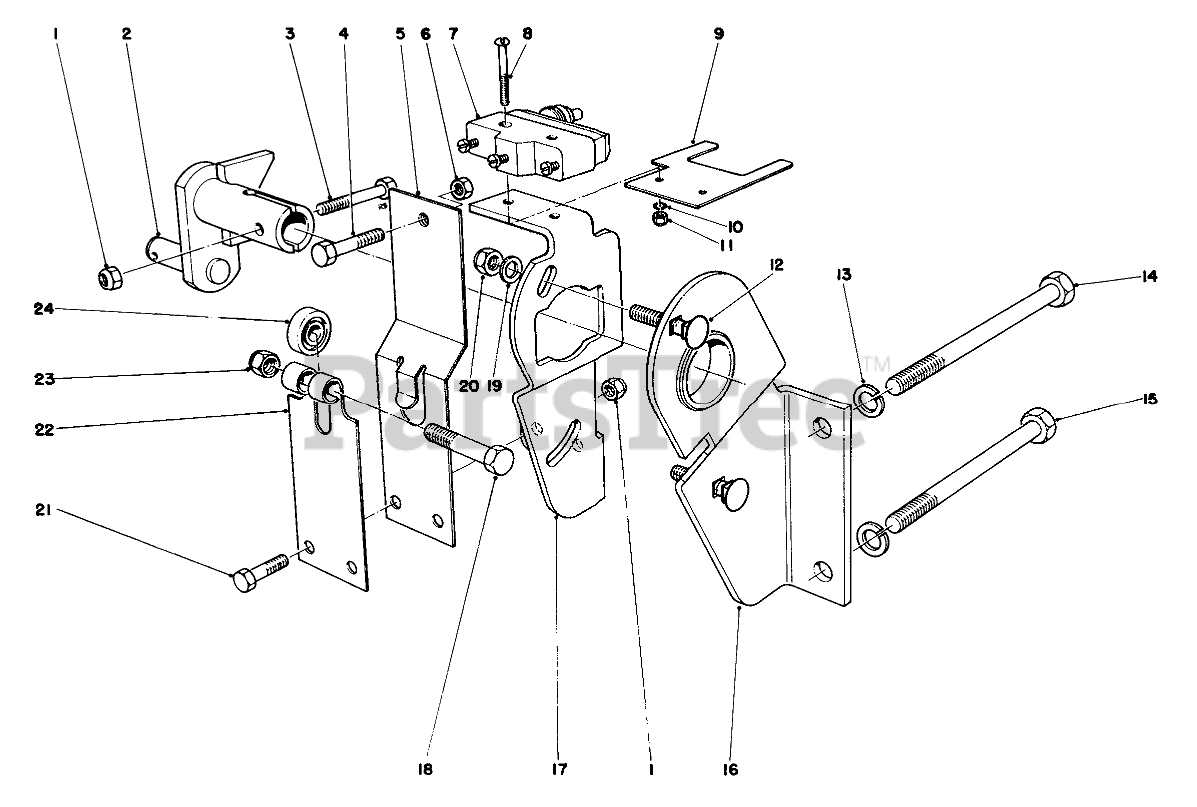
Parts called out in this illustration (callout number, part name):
1	NUT-LOCK, NI
2	Lever-Pump
3	SCREW-HH
4	SCREW-HH
5	EXTENDED LEAF SPRING ASM
6	NUT-HEX
7	Micro Switch
8	SCREW-MACHINE
9	STOP-SPRING, LEAF
10	WASHER-LOCK, INTERNAL
11	NUT-HEX
12	BOLT-CARR
13	WASHER-LOCK
14	SCREW-HH
15	SCREW-HH
16	Bracket-Mounting
17	PLATE-PUMP
18	SCREW-HH
19	WASHER-FLAT
20	NUT-LOCK, NI
21	SCREW-HH
22	SPRING-LEAF
23	NUT-LOCK, NI
24	BEARING-BALL
